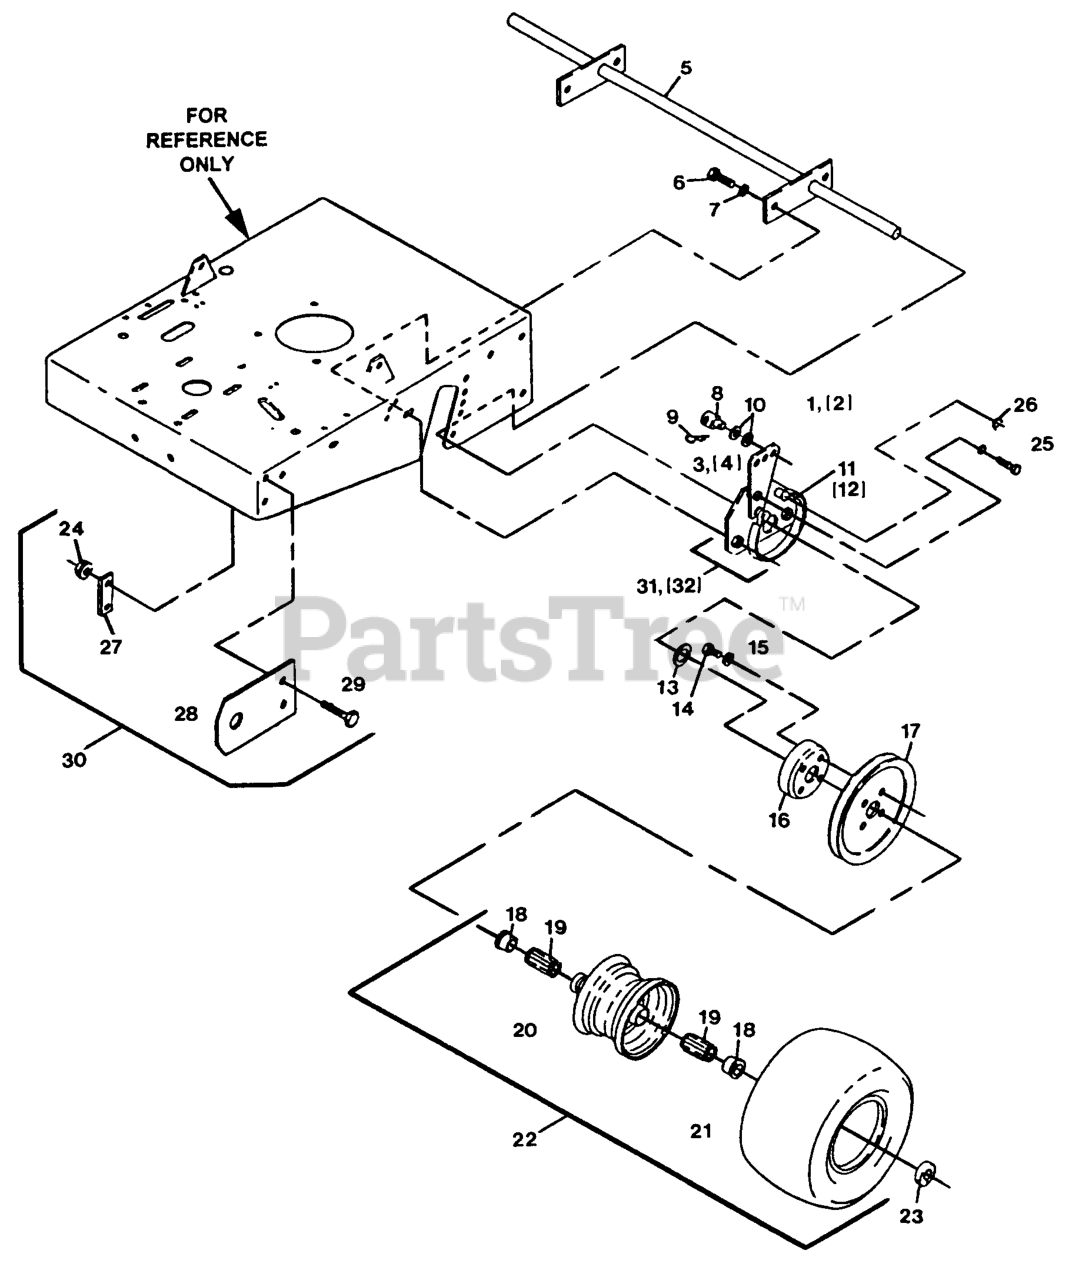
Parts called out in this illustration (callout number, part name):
1	WLD,BRAKE LEVER RH
8	SWIVEL,SHORT ADJUSTING
9	PIN-COTTER
12	BAND,BRAKE LH
13	WASHER-FLAT
15	WASHER-LOCK
17	SHEAVE,SPLIT STEEL 9 B
19	BEARING,ROLLER
23	COLLAR,LOCKING 7/8
28	MOUNT-HITCH
30	Viking 5-Speed Kit, Hitch Sulky
31	ASM,BRAKE LH
32	ASM,BRAKE RH
